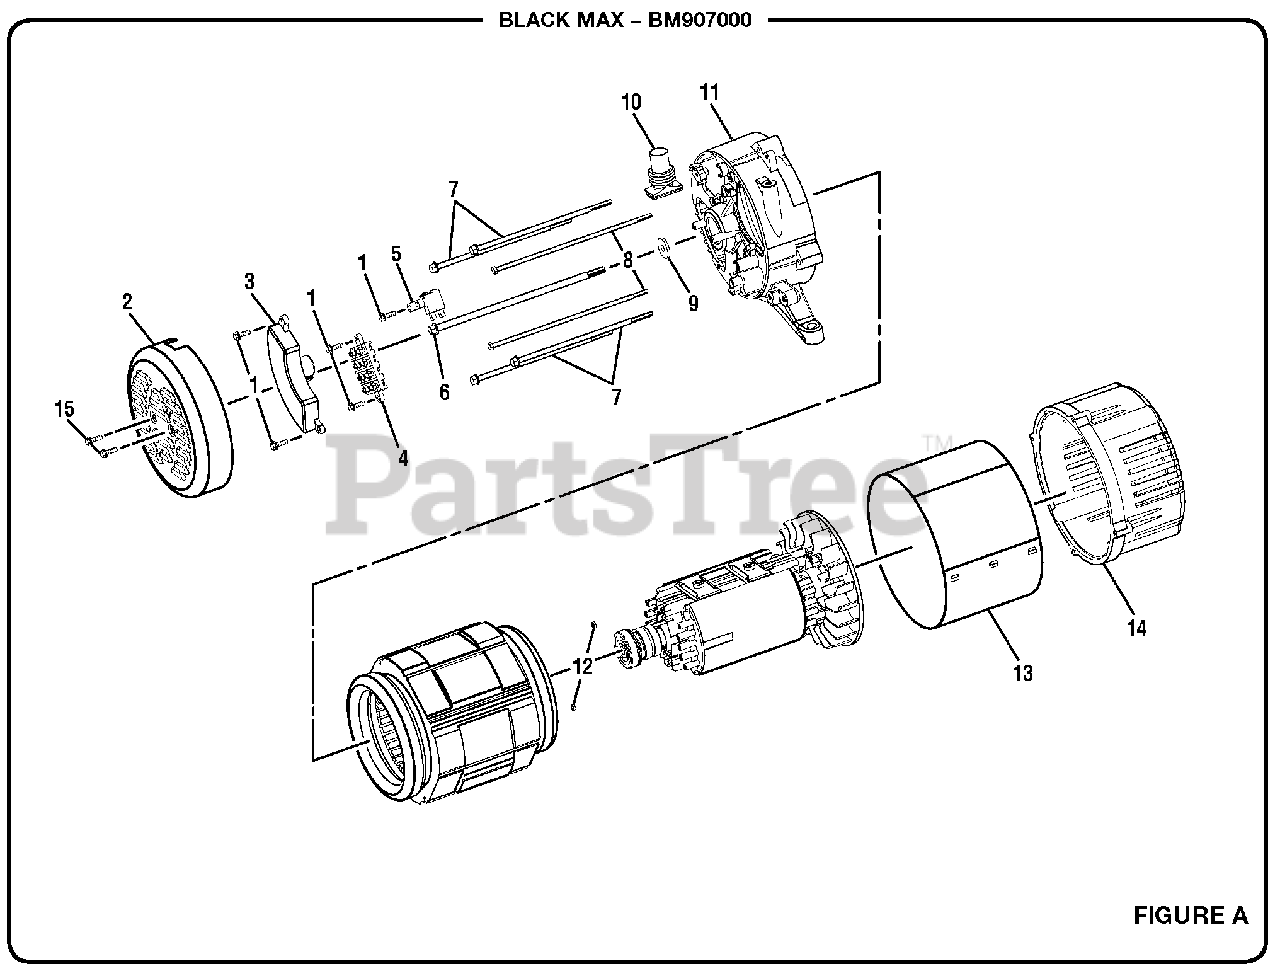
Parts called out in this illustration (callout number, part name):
1	Bolt (M5 x 16 mm, Hex Hd.)
2	Brush Cover
3	Automatic Voltage Regulator
4	Terminal Block
5	Brush Assembly
6	Bolt (5/16-24 x 235 mm, Hex Washer Hd.)
7	Bolt (M6 x 188 mm, Hex Washer Hd.)
8	Bolt (M5 x 210 mm, Hex Washer Hd.)
9	Washer (8 x 26 x 3t)
10	Rubber Boot
11	Bearing Housing
12	Hex Nut (M5)
13	Generator Head Cover
14	Adaptor Housing
15	Bolt (M5 x 12 mm, Hex Hd.)
